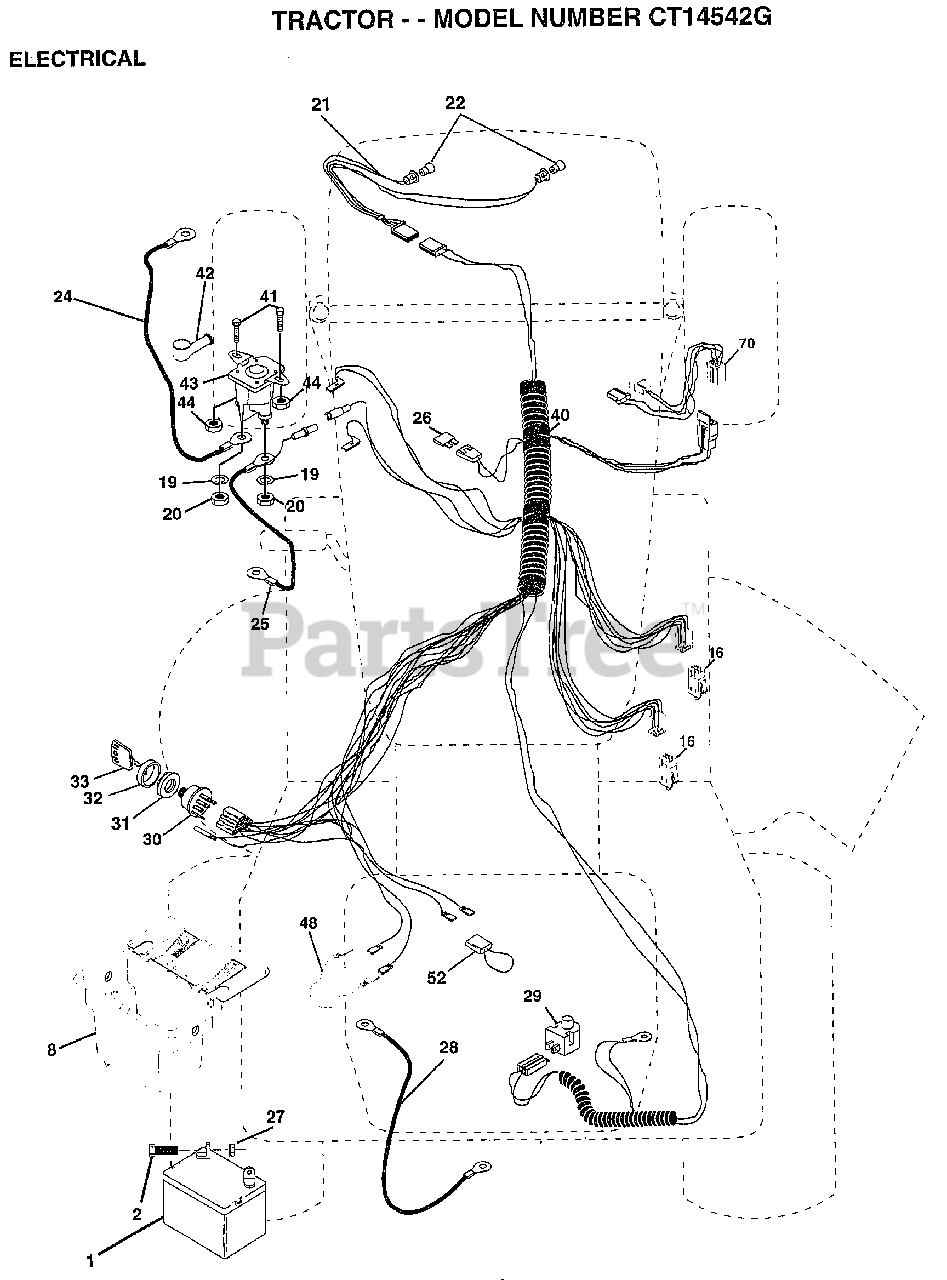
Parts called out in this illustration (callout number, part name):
2	BOLT LT
8	"CASE,BATTERY.MECH"
16	SWITCH INTERLOCK
20	NUT
21	HARNESS.ASM.LIGHT W/4152J
22	HEADLAMP BULB
24	"CABLE T, BATTERY"
25	CABLE.BTRY.6GA.RD
26	FUSE.15 AMP
27	NUT
28	CABLE T
29	SWITCH SEAT
30	SWITCH IGN 4POS
31	NUT IGNITION
32	COVER KEY SWITCH
33	KEY
40	HARNESS.IGNITION
41	BOLT HXHD FIN
44	NUT HXKEP 1/4X20
48	ADAPTER AMMETER
52	PROTECTION LOOP
70	HARNESS.ENGINE.B&S
